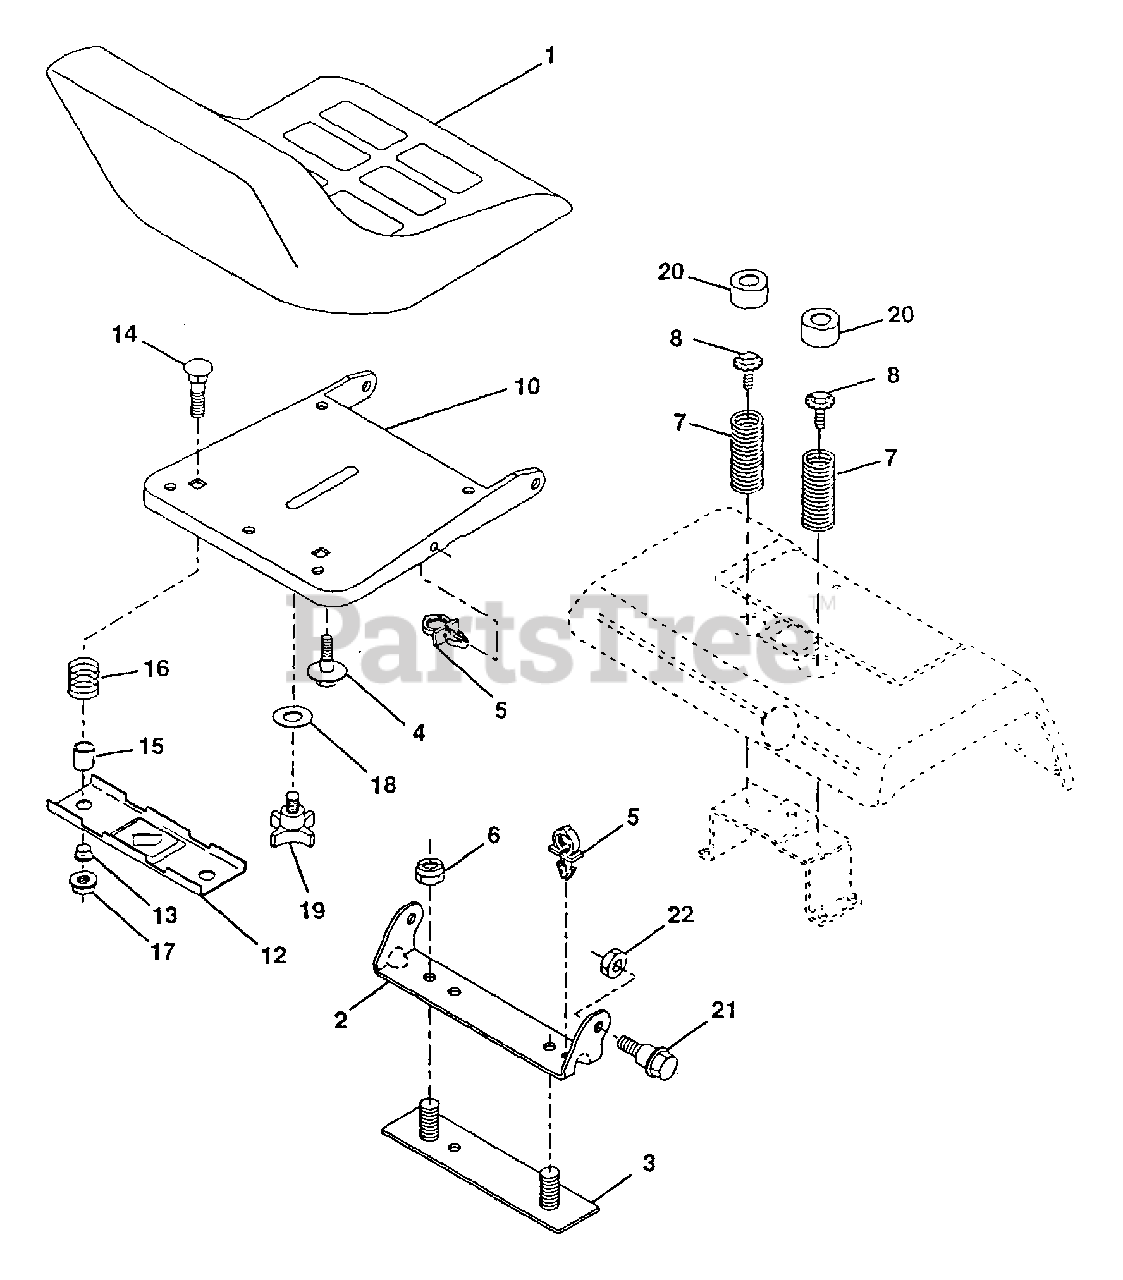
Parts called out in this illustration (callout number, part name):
1	Seat
2	Bracket, Pivot Seat
3	Strap, Fender
4	Bolt, Shoulder 5/16-18 X .62
5	Clip, Push In
6	Nut Crownlock 3/8-16 Unc
7	Spring, Seat Cprsn
8	Bolt 5/16-18 UNC x 3/4 w/Sems
10	Pan, Seat (AYP part number)
12	Bracket, Mounting Switch
13	Bushing, Snap
14	Bolt, Carriage 1/4-20 X 1-3(8 (AYP part number)
15	Spacer, Split
16	Spring, Cprsn
17	Nut, Lock 1/4 Lge Flg Gr. 5 (AYP part number)
18	Washer 17/32 X 1-3/16 X 12 Ga.
19	Knob, Seat 1/2-13 Unc
20	Cap, Spring Seat
21	Bolt, Shoulder 5/16-18 Unc (AYP part number)
22	Nut, Crownlock 5/16-18 Unc
